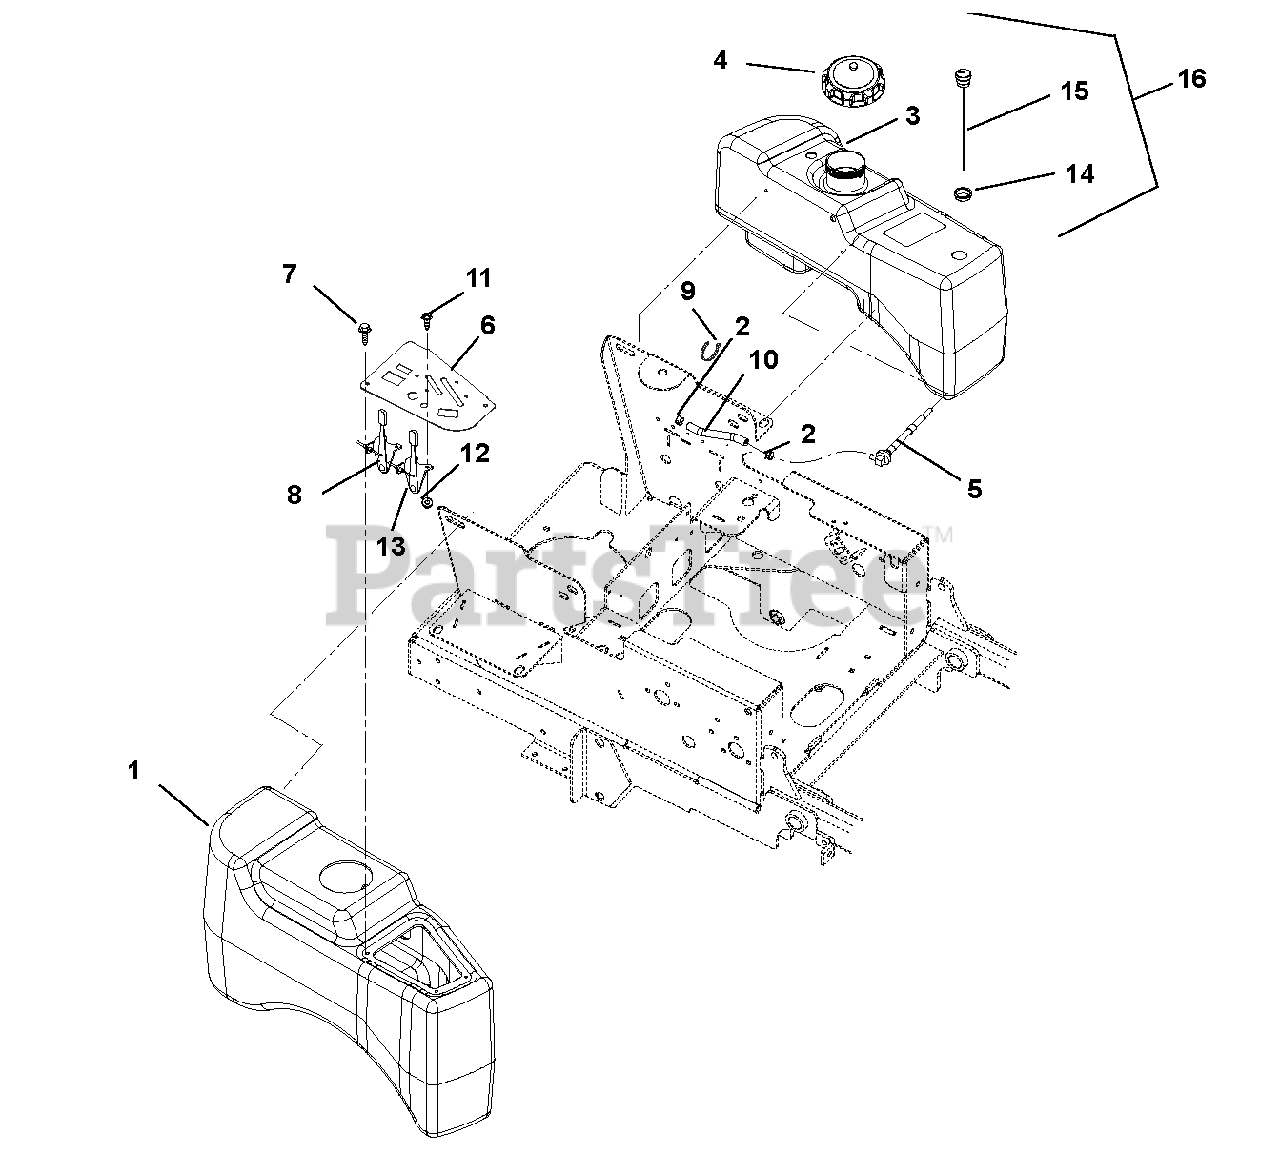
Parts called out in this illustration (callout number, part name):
1	FENDER, RH
2	CLAMP, FUEL LINE
3	TANK, LH FUEL
4	CAP,3.50" VENT-IN RATCHET FUEL
5	ASM, FUEL PICK-UP SML/MED TANK
6	INSTRUMENT PANEL - BLK
7	SCR-HEX .25X14-.75
8	CABLE, CONTROL
9	CABLE TIE LG 5-1/2
10	HOSE, .25 LOW-PERM BULK GAS
11	@SCR-MCH 10-24X.50 HWH YWZC
12	@NUT-LK-NYL 10-24 W/INSRT YWZC
13	CABLE, THROTTLE
14	GROMMET, FUEL GAGE
15	GAUGE, REMOTE FUEL 10.0"
16	HD, FUEL TANK ASSEMBLY
